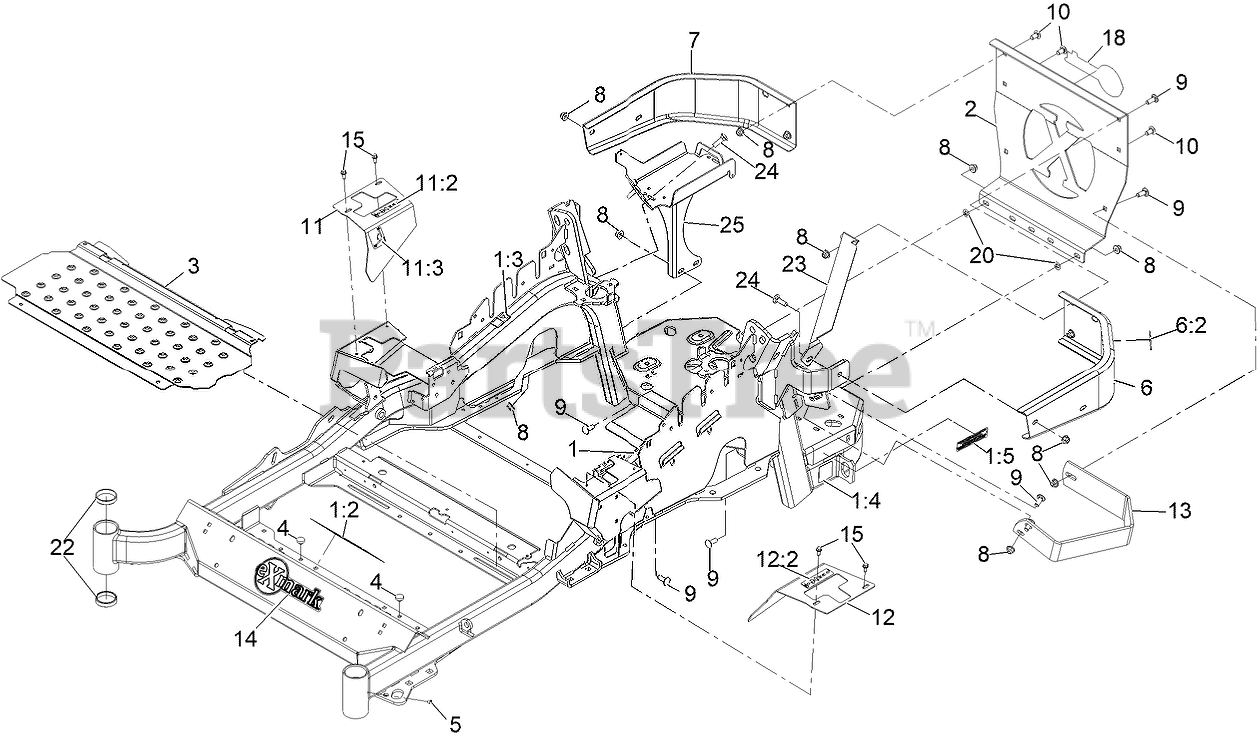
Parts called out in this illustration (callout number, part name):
1	Mainframe Service ASM - 48/52
1:2	DECAL-DANGER
1:3	DECAL-WARNING
1:4	DECAL-HAZARD, PINCHED FINGER
1:5	DECAL-ARRESTOR, SPARK
2	PLATE,REAR GUARD
6	LH BUMPER ASM
6:2	DECAL-WARNING
7	BUMPER-RH
8	NUT-HF, NI
9	SCREW-CARR
10	SCREW-CARR
11	RH MOTION CONTROL COVER ASM
11:2	DECAL-CONTROL, MOTION
11:3	DECAL-PARK BRAKE, CE
12	LH MOTION CONTROL COVER ASM
12:2	DECAL-CONTROL, MOTION
13	GUARD-MUFFLER
14	DECAL-EXMARK
15	SCREW-HWH
18	DECAL, EXMARK LOGO
20	NUT-PUSH
22	CUP-BEARING
24	BOLT-CARR
25	BATTERY MOUNT ASM
